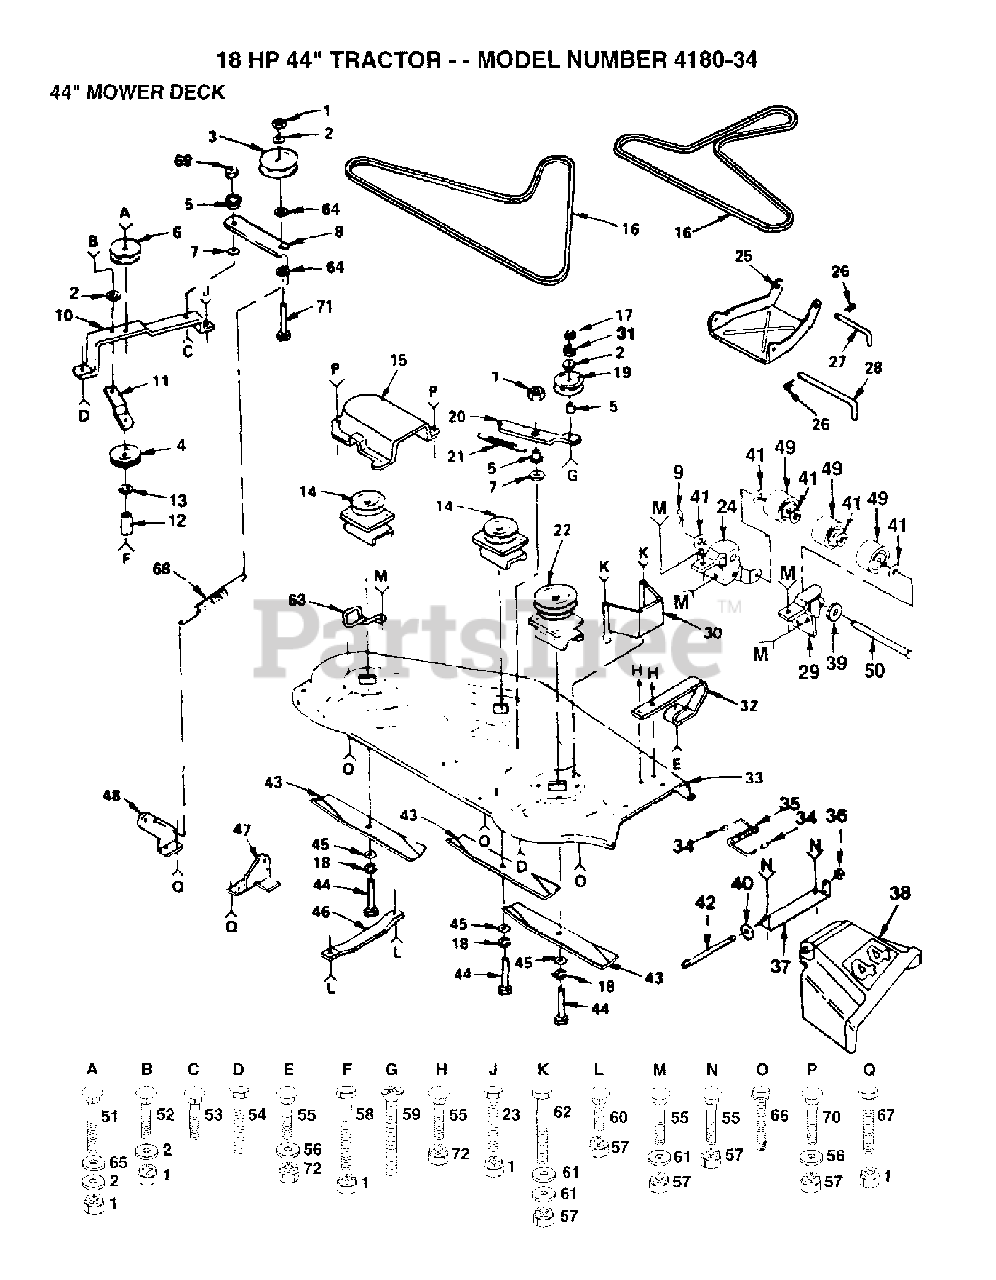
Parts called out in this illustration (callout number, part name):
1	LOCKNUT
3	PULLEY IDLER
4	IDLER-FLAT T
5	SPACER RETAINER
6	IDLER-INSIDE T
7	WASHER, WEAR LT (1 2)
8	ARM IDLER
9	COTTER PIN
10	BAR-SUPPORT YT
11	BRACE-IDLER YT
14	MANDRELL
15	GUARD YT
16	V-BELT T
17	NUT.HEX.3/8-16UNC
19	IDLER.FLAT.GTV
20	ARM-IDLER YT
21	SPRING T
22	JACKSHAFT YT
23	BOLT
24	BRACKET LH YTH
25	LINK,PARALLEL
26	SPRING.RETAINER
27	ROD,FRT PARALL LT
28	HINGE PIN T
29	BRACKET RH YTH
30	GUARD BELT HYT
31	WASHER, LOCK 3/8
32	RUNNER-RH YTV
33	HOUSING
34	CAP-SLEEVE LT
35	DEFLECTOR SPRG T
36	NUT PUSH M
37	BRACKET, DEFLECTOR
38	DEFLECTOR SHIELD
39	WASHER
40	WASHER
42	ROD-HINGE T
43	BLADE
44	BOLT.3/8-24X1-1/2
45	WASHER
46	RUNNER LH
47	BRKT SUSP REAR RH
49	ROLLER T
50	PIVOT PIN T
51	BOLT
55	BOLT
56	WASHER
57	LOCKNUT
59	SCREW YT
60	BOLT
61	WASHER M
63	BELT RETIANER
64	WASHER
65	WASHER
68	SPRING.EXT.8.5"
69	LOCKNUT
70	BOLT.5/16-18.
71	BOLT
72	Lock Nut
